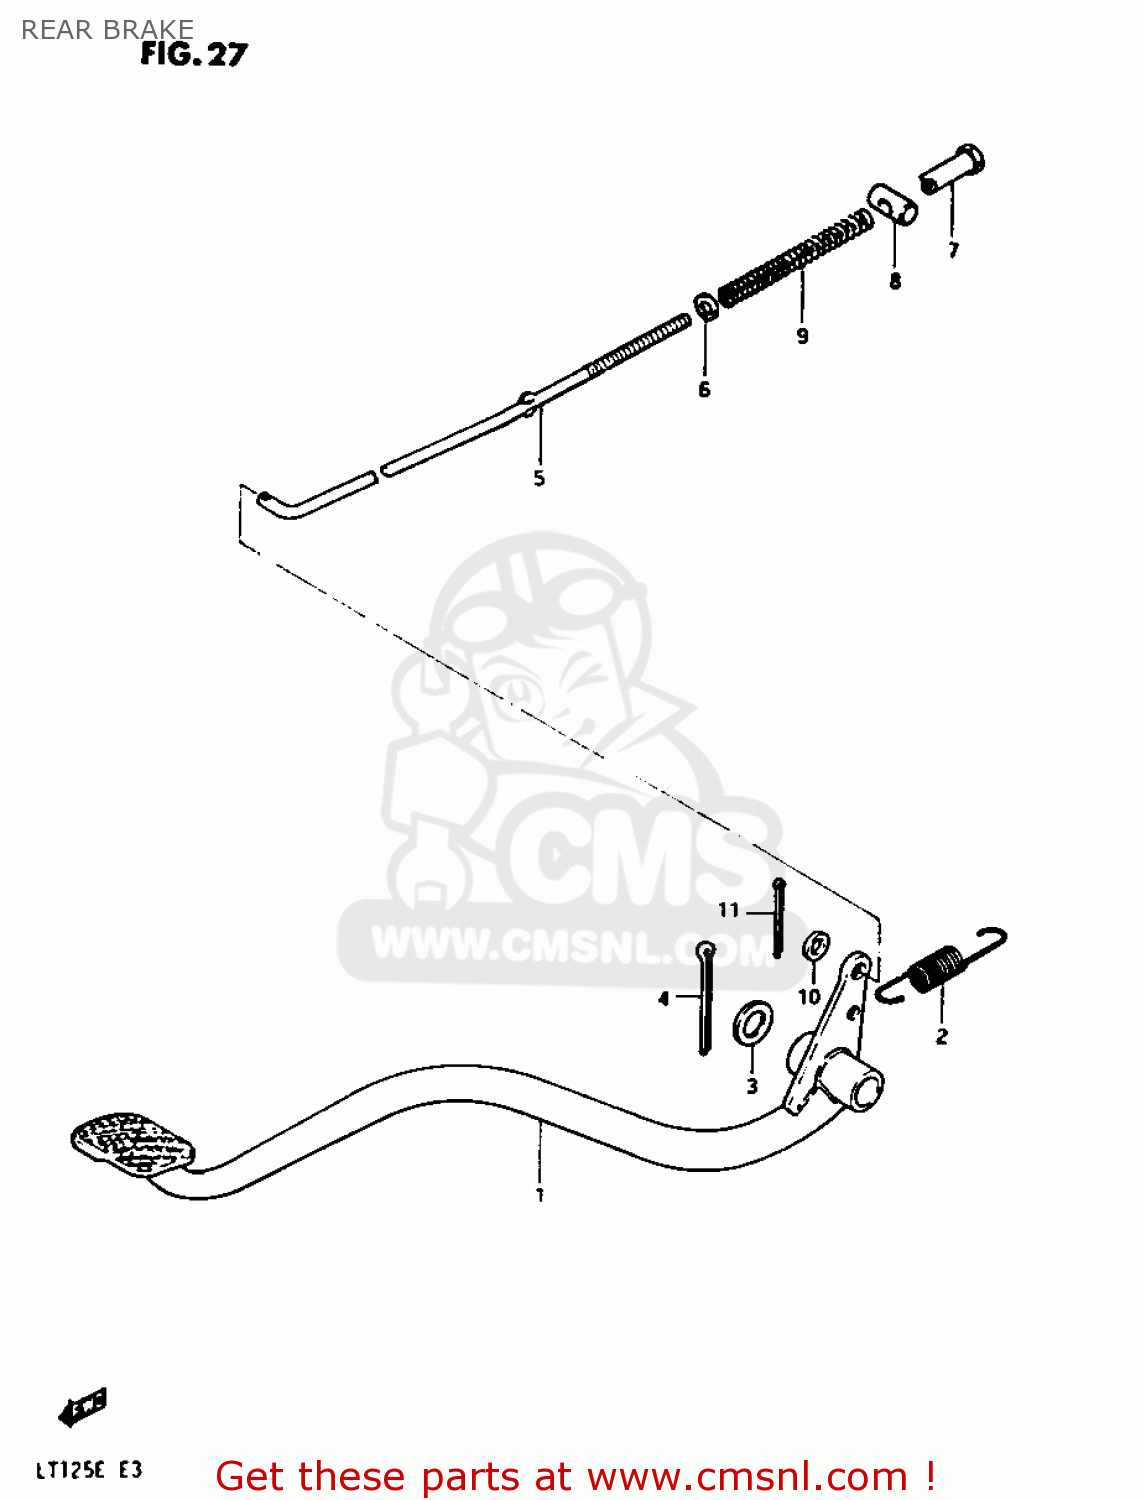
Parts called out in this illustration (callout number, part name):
1	PEDAL,BRAKE
2	SPRING
3	WASHER(15.5X26X2.3)
4	COTTER PIN
5	ROD ASSY,RR BRAKE
6	WASHER
7	NUT
8	PIN
9	SPRING
10	WASHER
11	PIN 20X20
